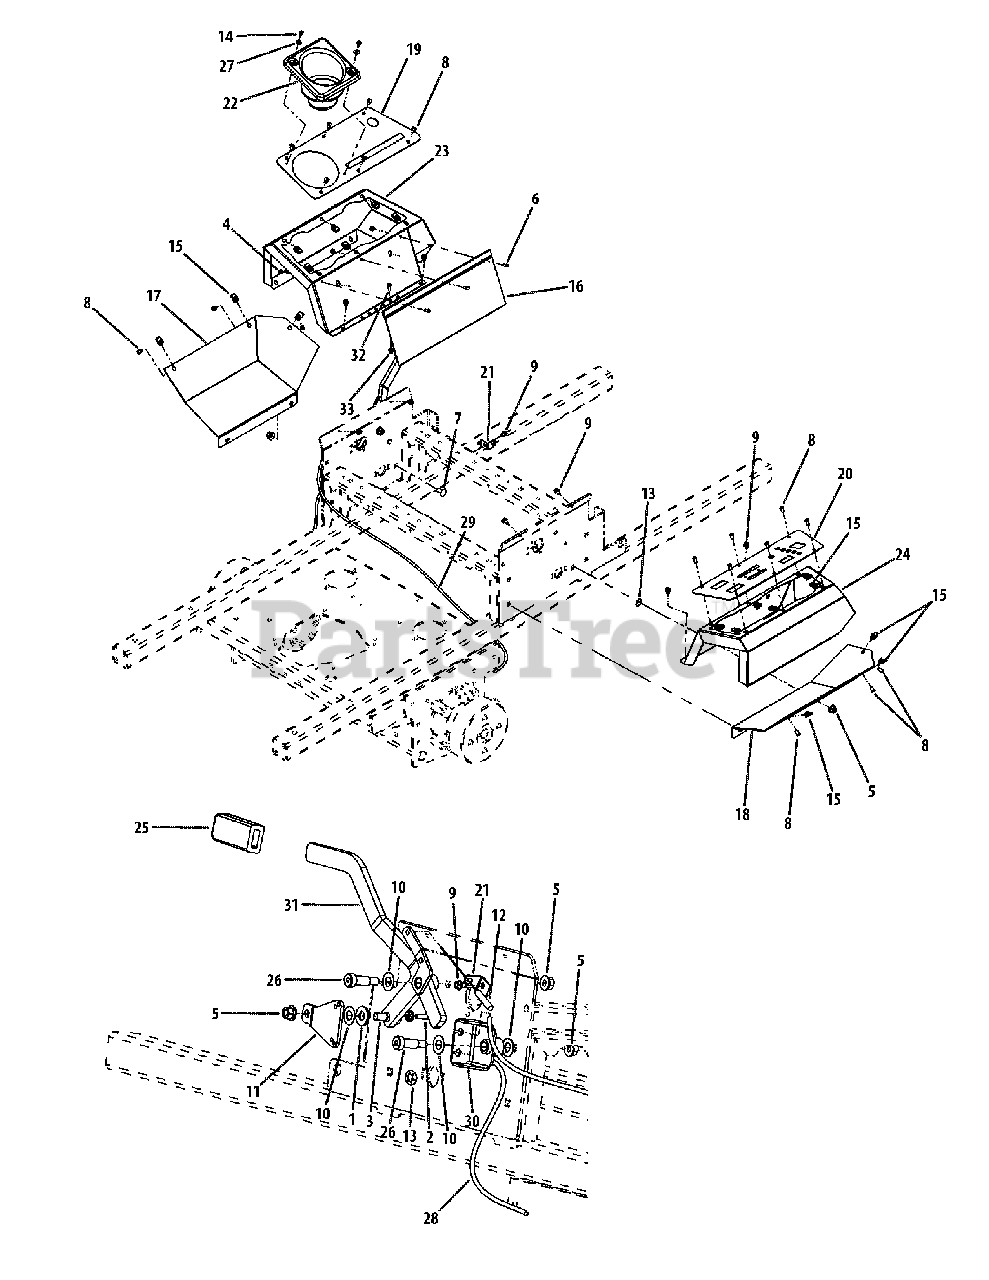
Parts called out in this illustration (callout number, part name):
1	Washer, 1/2 Zinc
2	Carriage Bolt, 3/8-16, 1.00
3	Shoulder Bolt, 1/2 x 1/2
4	Lock Nut, Nylon Insert, 10-32
5	Flange Lock Hex Nut, 3/8-16
6	Machine Screw, 10-32 x 5/8
7	Carriage Bolt, 3/8-16 x .75
8	Screw Button Head, 1/4-20 x .5
9	Screw, TT, 1/4-20, 0.5, Washer
10	Washer, .508 ID x 1.0 OD x .020
11	Centering Bracket
12	Left Hand Brake Cable
13	Push Retainer, 3/8
14	Screw, #10-32 x 0.500
15	U-Nut, 1/4-20
16	Bag, Debris Storage
17	Lower Panel, LH
18	Lower Panel, RH
19	Control Panel Cover, LH
20	Control Panel Cover, RH
21	Brake Cable Mounting Bracket
22	Cup Holder
23	Control Panel, LH
24	Control Panel, RH
25	Parking Brake Grip
26	Shoulder Bolt, 1/2 x 1.00, 3/8-16
27	Washer, 3/16
28	Brake Cable, LH
29	Brake Cable, RH
30	Brake Cable Bracket
32	Screw, Hex, Cap, 1/4-20 x .75
33	Lock Nut, 1/4-20
